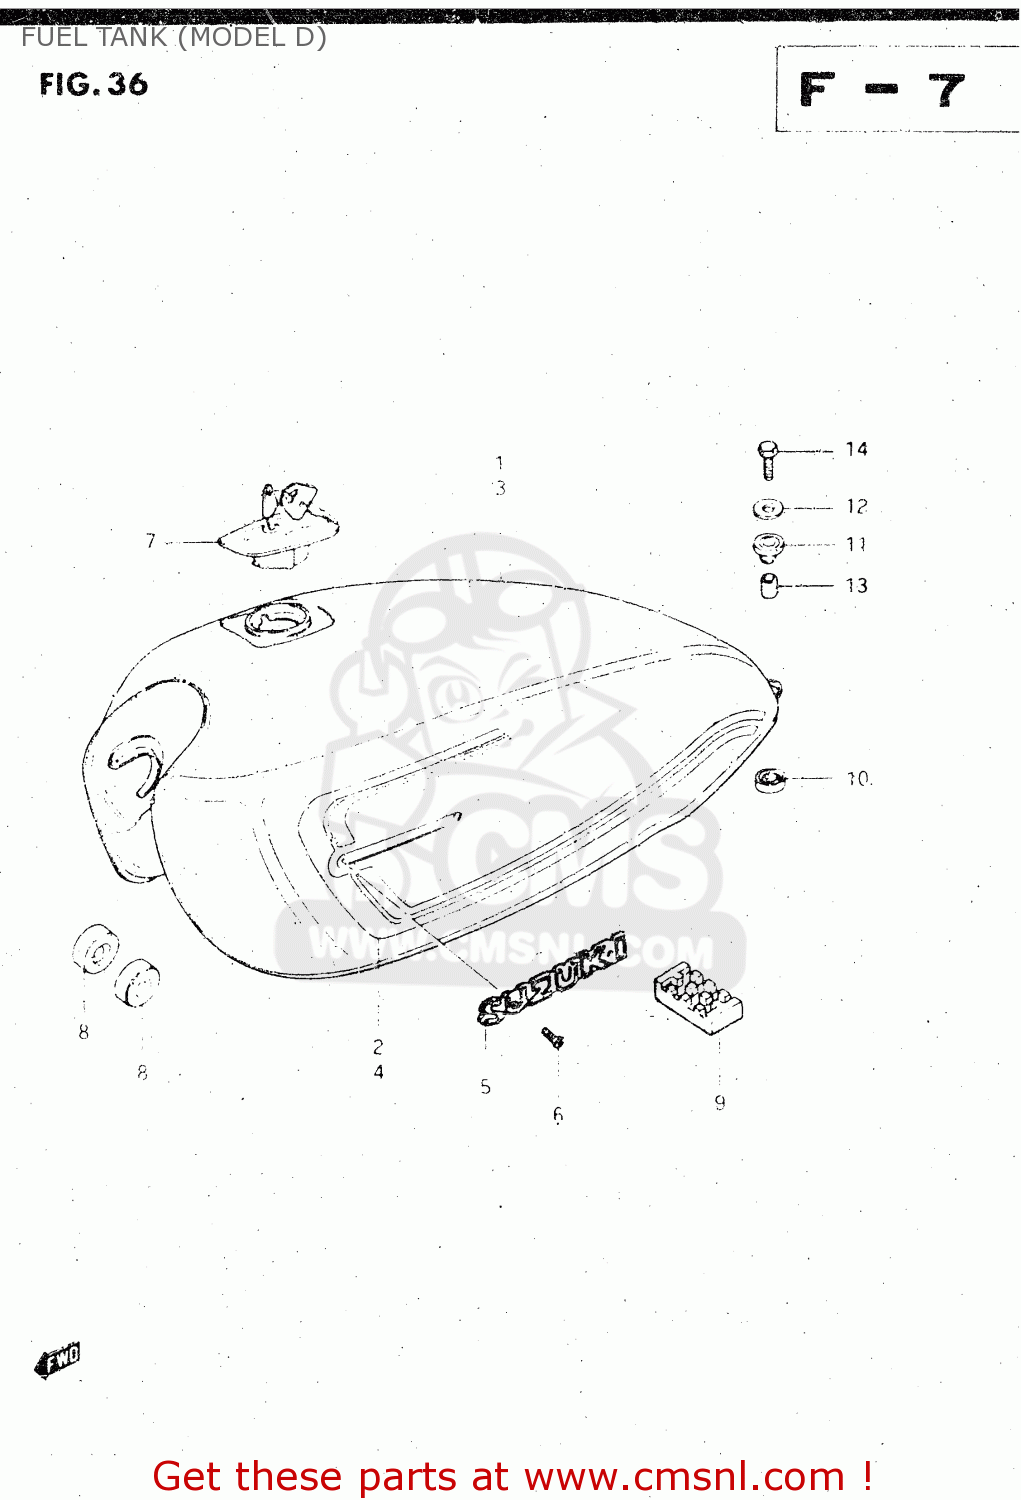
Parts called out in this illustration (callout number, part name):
1	TANK, FUEL (RED)
2	TAPE SET
3	TANK, FUEL (BLUE)
4	TAPE SET
5	EMBLEM,FUEL TANK
6	SCREW 3X6
7	CAP SET,FUEL TANK
8	CUSHION
9	CUSHION,FUEL TANK CTR
10	CUSHION
11	CUSHION
12	WASHER (6.5X24X1.6)
13	SPACER
14	BOLT
